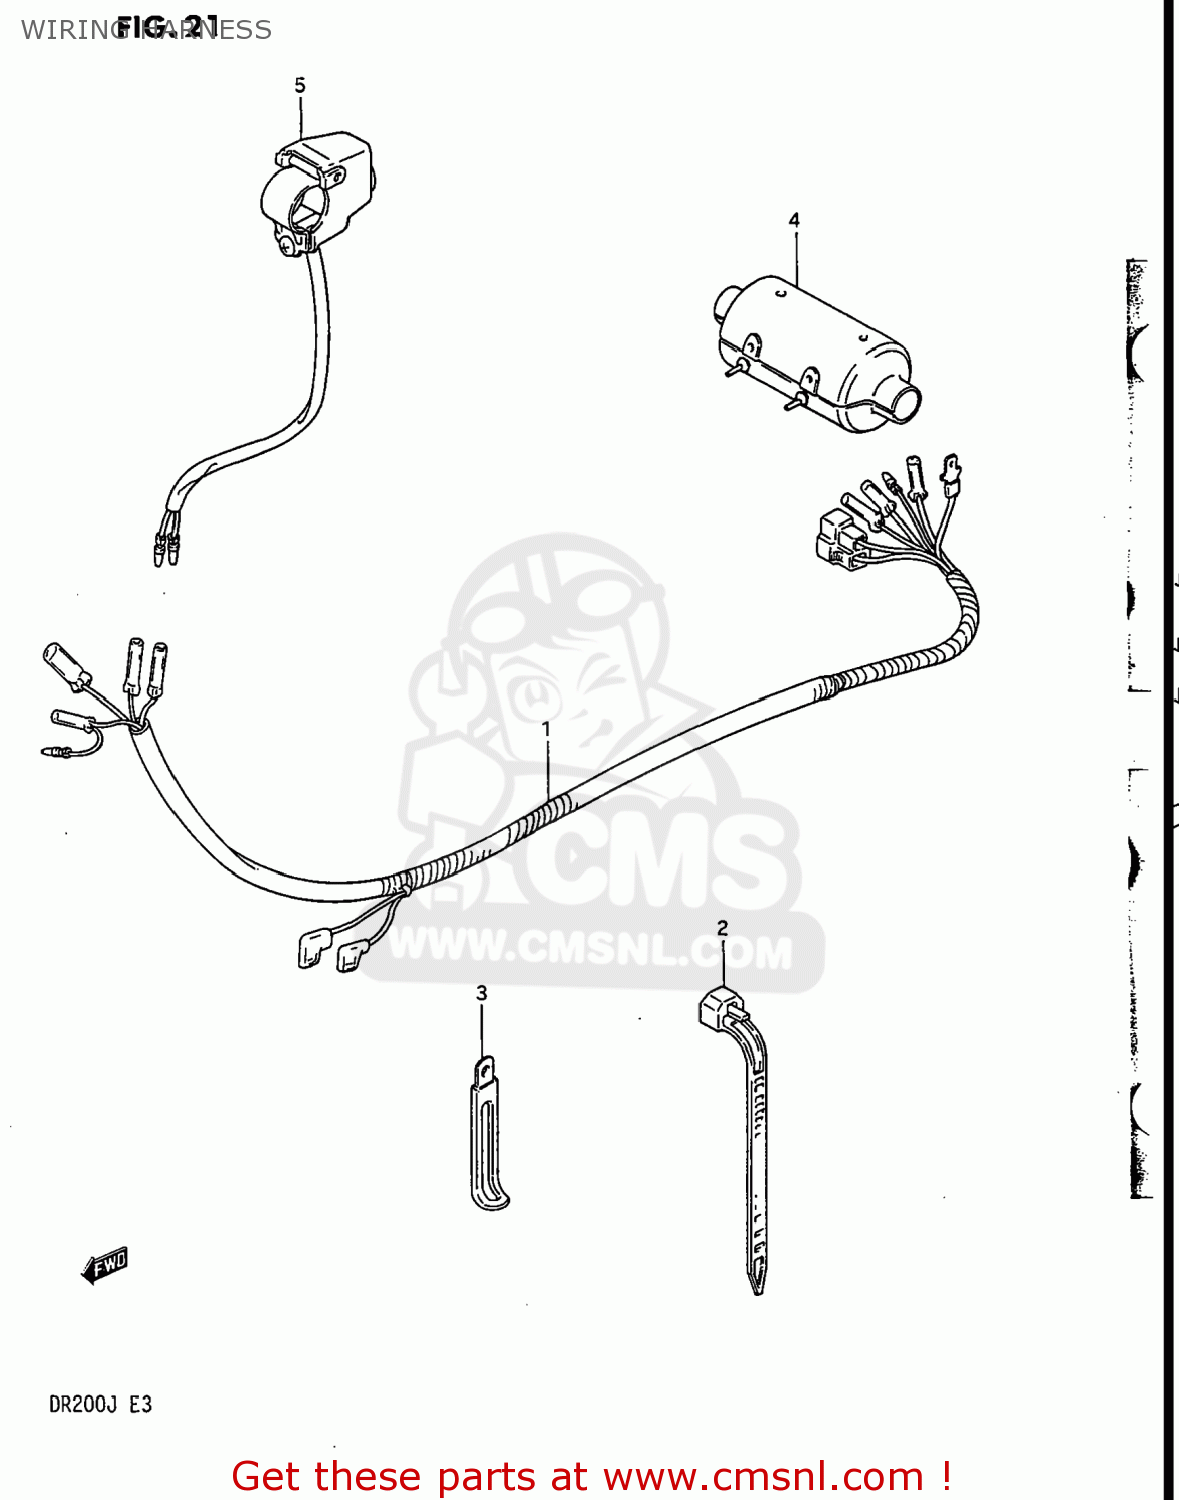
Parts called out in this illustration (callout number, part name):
1	HARNESS,WIRING
2	CLAMP(L:125)
3	CLAMP
4	BOOT,WIRING HARNESS
5	SWITCH ASSY,ENGINE STOP
